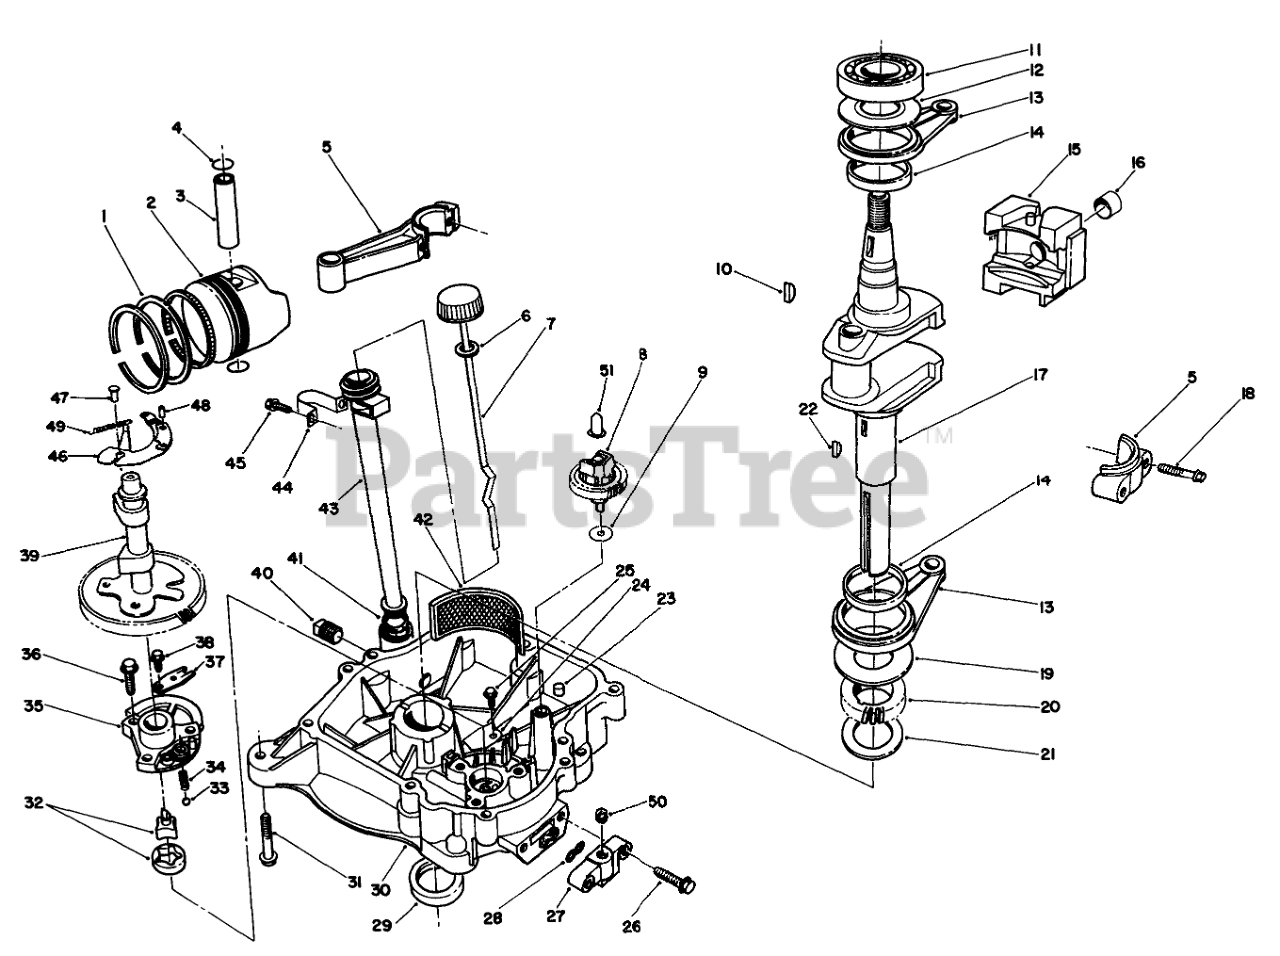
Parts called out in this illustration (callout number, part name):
1	Piston Ring Set
3	Pin-Piston
4	Ring-Snap
5	Rod ASM Incl #10 11
6	Gasket
8	Governor ASM
11	Ball Bearing
13	Rod Incl #8
15	Weight
17	Crankshaft
20	Gear
21	Shim (1.18)
25	Bolt
26	Bolt
31	Bolt-Flanged (8X45)
32	Pump ASM-Oil
35	Cover-Pump
36	Bolt-Flanged (8X25)
37	Plate
38	BOLT-FLANGED (6X10)
39	Camshaft
40	Plug
41	O-RING (16mm)
42	Filter-Oil
45	Bolt
46	Decompressor
51	Sleeve
